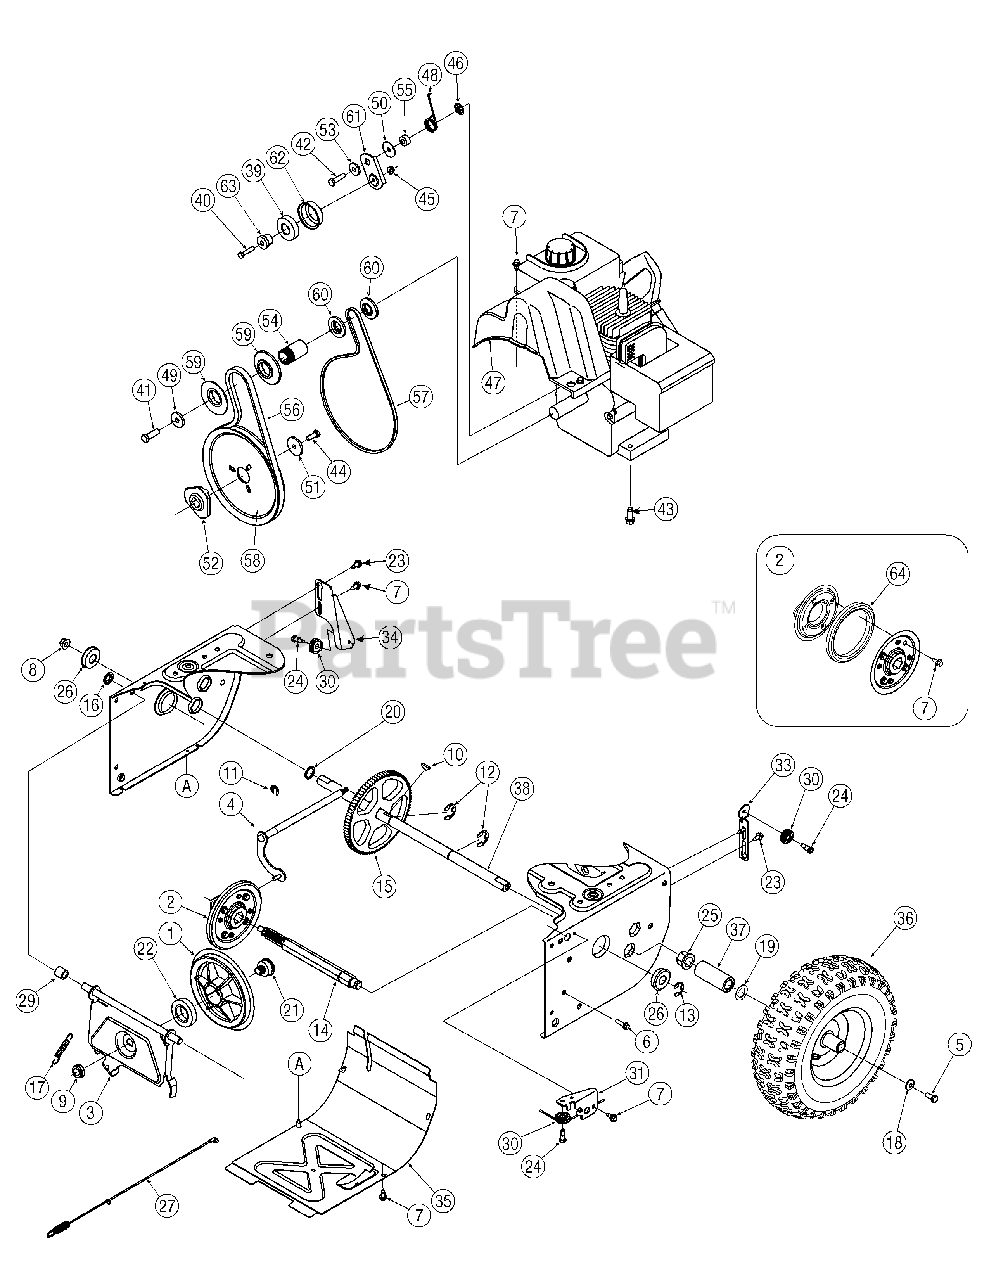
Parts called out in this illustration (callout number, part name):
1	Disc, Friction Wheel
2	Friction Wheel Assembly, 5.5 OD
4	Shift Assembly, Rod
5	Hex Screw, 5/16-24, .750, Gr5
6	Screw, 1/4-20, 1.000
7	Screw 1/4-20x.625
8	Nut, Flange Lock, 3/8-16, Nylon
9	Nut, Jam Lock, 5/8-18, Gr5, Nylon
10	Key, Hi Pro, 3/16 x 3/4 Dia
11	E-ring, .500 Dia.
12	E-ring, Retaining, .875 Dia.
13	E-ring, .750 Dia.
14	Hex Shaft, .8125, 7-Tooth
15	Gear, 80-Tooth
16	Speed Nut, .500
17	Extension Spring
18	Washer, Bell, .340 x .872 x 0.60
19	Washer, Flat, .793 x 1.24 x 0.60
20	Washer, Flat, .75 x 1.00 x .060
21	Pin, Friction Disc
22	Ball Bearing, 30 x 55 x 13
23	Screw, Shoulder, .373 x .10, 1/4-20
24	Screw, 1/4-28, .375
25	Bearing, Hex Flange x .75 ID
26	Bearing, Ball, 17 x 40 x12
27	Clutch Cable, Wheel, 44.95"
27	Clutch Cable, Auger, 47.23"
29	Spacer, .508 ID x .75 OD x .68
30	Roller, Cable
36	Wheel Assembly Complete - 13" x 4"
36	Wheel Assembly Complete - 15" x 4"
37	Spacer, 1.25 x .75 x 3.0
37	Spacer, 1.25 x .75 x 1.50
38	Axle, .75 x 20"
38	Axle, .75 x 22"
39	Ball Bearing
40	Hex Screw, 1/4-20, 1.25, Gr5
41	Hex Screw, 3/8-24, 1.25, Gr8
42	Hex Screw, 5/16-24, 1.25, Gr5
43	Screw, Sems, 3/8-16, 1.00
44	Hex Screw, 5/16-24, .875, Gr8
45	Nut, Flange Lock, 1/4-20, Nylon
46	Nut, Push-on, .25 Dia.
47	Cover, Belt
48	Spring, Torsion, .850 ID x .354
49	Washer, Flat, .406 x 1.25 x .06
50	Washer, Flat, .330 x 1.25 x .06
51	Washer, Flat, .34 x 1.50 x .150
52	Pulley, Adapter, .75 Dia.
53	Spacer, Shoulder
54	Spacer, .875 ID x 1.185 OD
55	Spacer, .340 x .750 x .360
56	Belt, Auger Drive
57	Belt, Wheel Drive
58	Pulley, Auger Drive, 8.1 x .5
59	Pulley, Half, V x 2.600 OD
60	Pulley, Half, 1/4-V x 1.5 OD
61	Idler Bracket, Wheel Drive
62	Sleeve, Bearing Idler
63	Spacer, Shoulder, .26 x .79 x.538
64	Rubber, Friction Wheel, 5.5 OD
